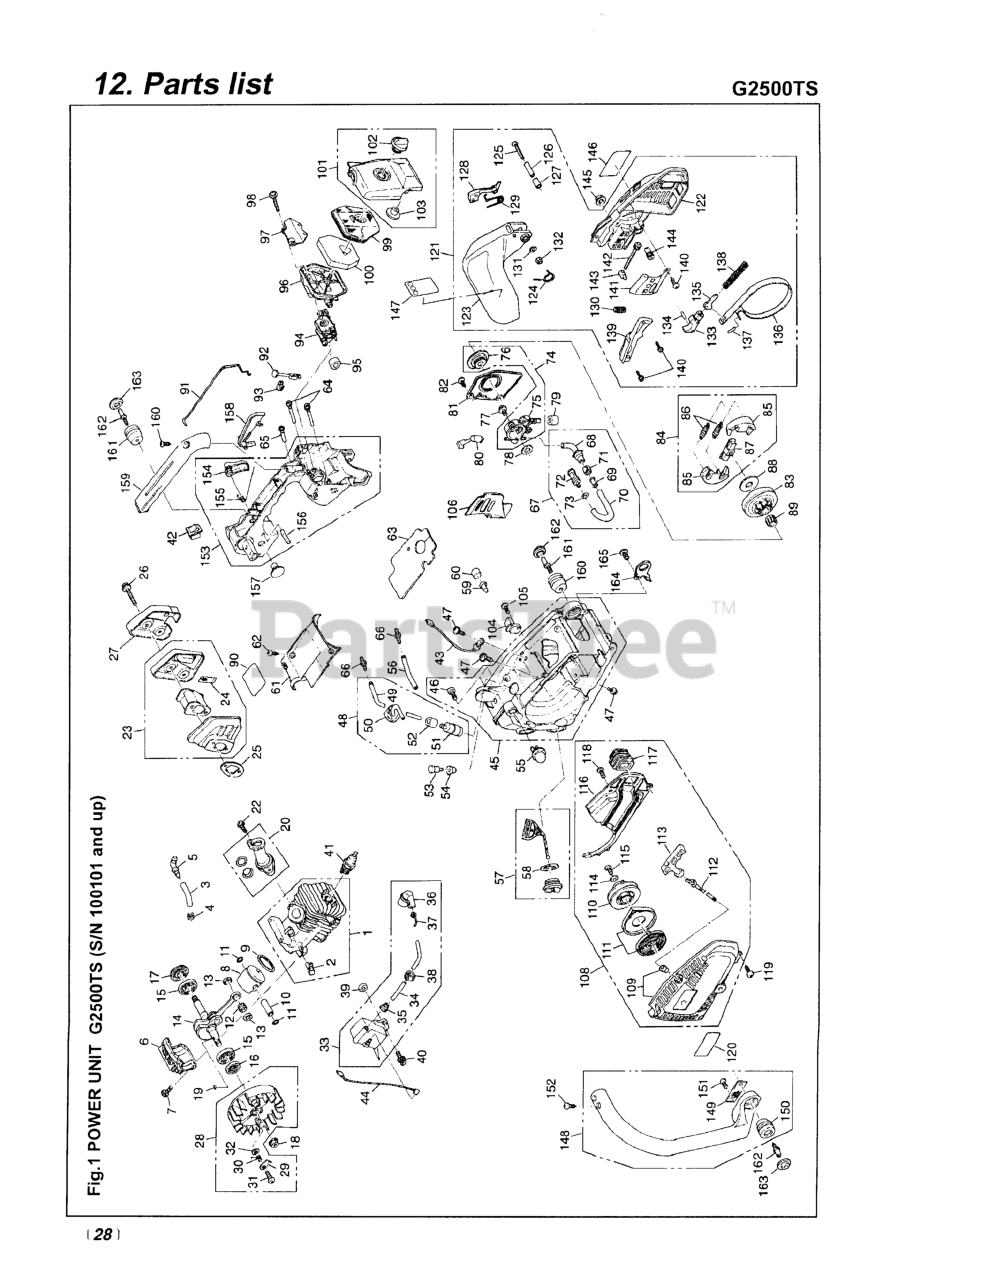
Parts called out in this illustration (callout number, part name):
1	CYLINDER COMP.
6	CRANKCASE
7	BOLT, M5 X 20
9	RING, PISTON
10	PIN, PISTON
11	RING, SNAP (RPLS 1101-41320)
12	BEARING (RPLS 1140-41330)
13	WASHER
14	SHAFT COMPLETE
16	OIL SEAL(RPLS 2841-21210)
19	KEY
20	PIPE SET (REPLACES 2841-06010)
22	SCREW (REPLACES -30414)
23	MUFFLER ASSEMBLY
24	ARRESTER, SPARK
25	GASKET (REPLACES 3304-15210)
26	SCREW
27	COVER, MUFFLER
28	ROTOR ASSEMBLY
29	PAWL
30	SPRING, RETURN
31	SCREW
32	WASHER
33	MODULE ASSEMBLY
35	CAP
36	CAP, PLUG
37	SPRING PLUG (RPLS 3310-71320)
40	BOLT, M4 x 20
42	SWITCH ASSEMBLY
43	CORD, EARTH
44	CORD, SWITCH
45	2841-31107 (REPLACES -31103)
47	SCREW
48	PIPE ASSY (RPLS 2841-31201)
49	PIPE, FUEL
50	GROMMET (RPLS 2841-31251)
51	5500-85400 (RRLS. 1750-85300)
53	BREATHER ASSEMBLY
54	GROMMET
55	PUMP ASSEMBLY
56	PIPE
57	CAP ASSY.
58	GASKET
59	VALVE (RPLS -23120)
60	SEAL, BREATHER
61	COVER, TOP
62	SCREW
63	MAT(RPLS -31920)
65	PIPE
66	JOINT (USE 3350-34320)
67	PIPE,OIL COMPLETE
68	PIPE, OIL
72	FILTER, OIL (RPLS -23130)
73	RING, SNAP (RPLS 1101-41320)
75	PUMP, OIL
76	WORM GEAR
77	SCREW (REPLACES -30414)
78	WASHER
79	SEAL
80	PIPE, OUTLET
81	COVER, PUMP
82	SCREW
83	DRUM, CLUTCH
84	CLUTCH ASSY (RPLS. 2841-51201)
89	BEARING
90	LABEL (G2500TS)
91	ROD, THROTTLE
92	ROD, CHOKE
93	GROMMET
94	CARBURETOR
97	PLATE
99	CLEANER, AIR
100	ELEMENT
101	COVER COMP.
102	KNOB (RPLS 3356-83322)
104	CATCHER, CHAIN (RPLS. -53411)
106	PLATE, GUIDE-A
108	STARTER, RECOIL
109	CASE, RECOIL COMPLETE
111	SPRING COMPLETE
113	KNOB (RPLS -75420)
114	WASHER, FLAT (USE 182303)
116	COVER, FAN
117	PIPE, AIR
118	SCREW
119	SCREW
122	COVER, CHAIN
125	SCREW
127	SPACER (RPLS -54210)
131	WASHER, M5 X .8
132	NUT (B)
133	LEVER, BRAKE COMPLETE
135	ARM, SLIDE
137	PIN
138	SPRING, BRAKE (RPLS. 50030121)
140	SCREW (REPLACES 50030272)
142	SCREW
143	NUT
144	GEAR
145	NUT
147	LABEL,WARNING
148	HANDLE ASSY (RPLS 2841-32100)
149	STOPPER (RPLS 2841-32150)
150	DAMPER
153	HANDLE, RIGHT COMP
155	SPRING
159	COVER, GRIP
160	SCREW
161	DAMPER
162	BOLT, STOPPER
163	CAP, DAMPER
164	HANGER
165	SCREW (REPLACES 50030272)
